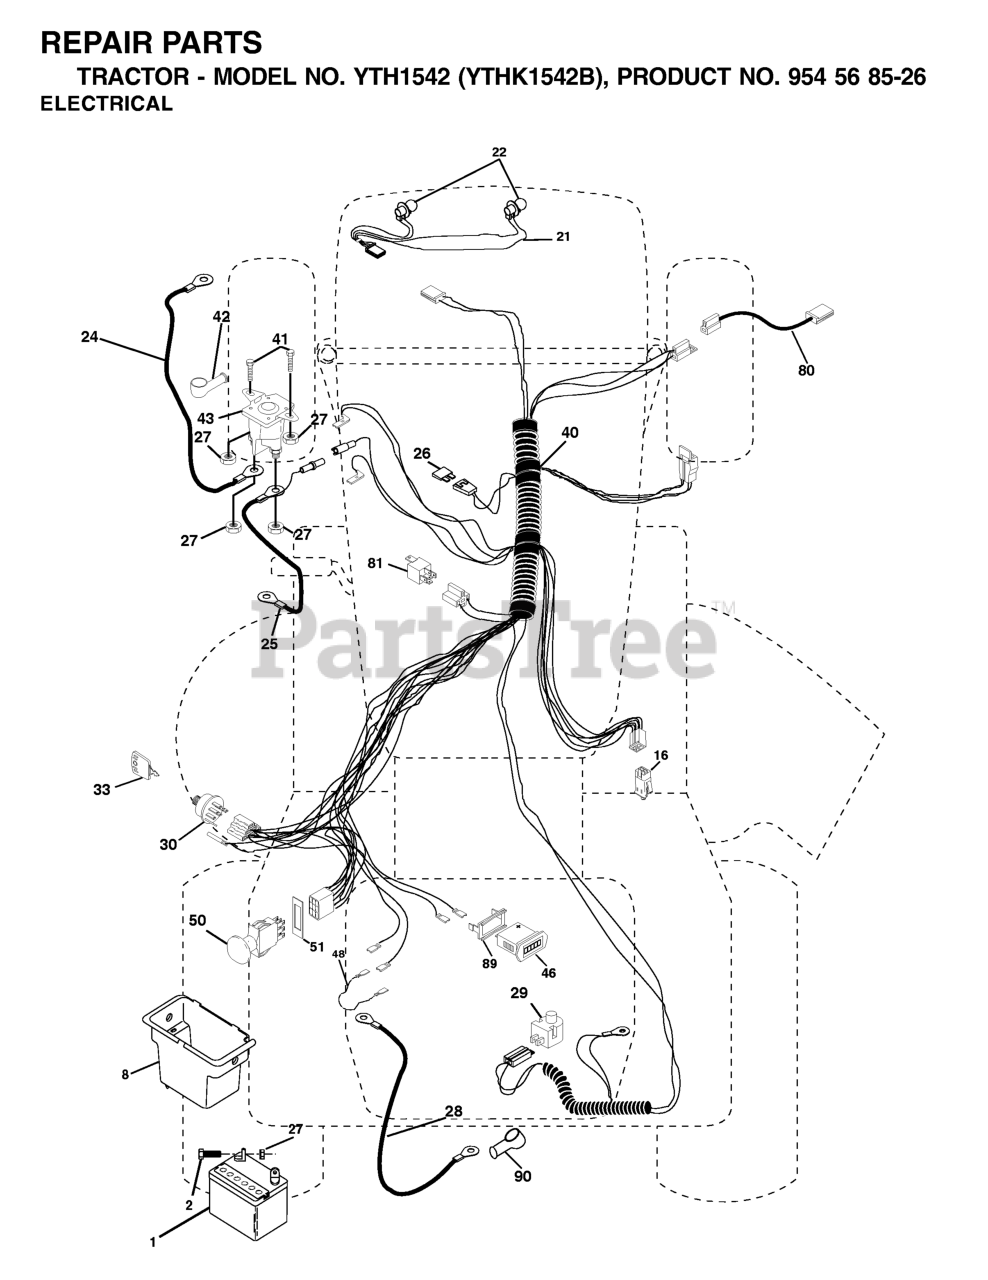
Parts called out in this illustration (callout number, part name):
1	Battery 12 Volt 25 Amp
2	BOLT.HEX.1/4.X.3/4.DICHROMATE
8	BOX.BATTERY.FENDER
16	SWITCH INTERLOOK PUSH-IN
21	HARNESS.ASM.LIGHT WSL
24	BATTERY CABLE GT
25	CABLE BATTERY
26	FUSE 20AMP
27	NUT
28	CABLE T
29	PLUNGER SWITCH (COLOR:OLIVE)
30	IGNITION SWITCH
33	KEY MLD GEN DELTA
40	HARNESS IGN.
41	BOLT
42	TERMINAL COVER
43	SOLENOID
46	HOUR METER
48	ADAPTER.AMMETER
50	RP.PTO.SWITCH.8 TERMINAL.BLACK
51	FRAME RETAINING RING
80	HARNESS, CLUTCH
81	RELAY.ASSY.T
89	BRACKET SNAP-IN HOURMETER
90	COVER TERMINAL
